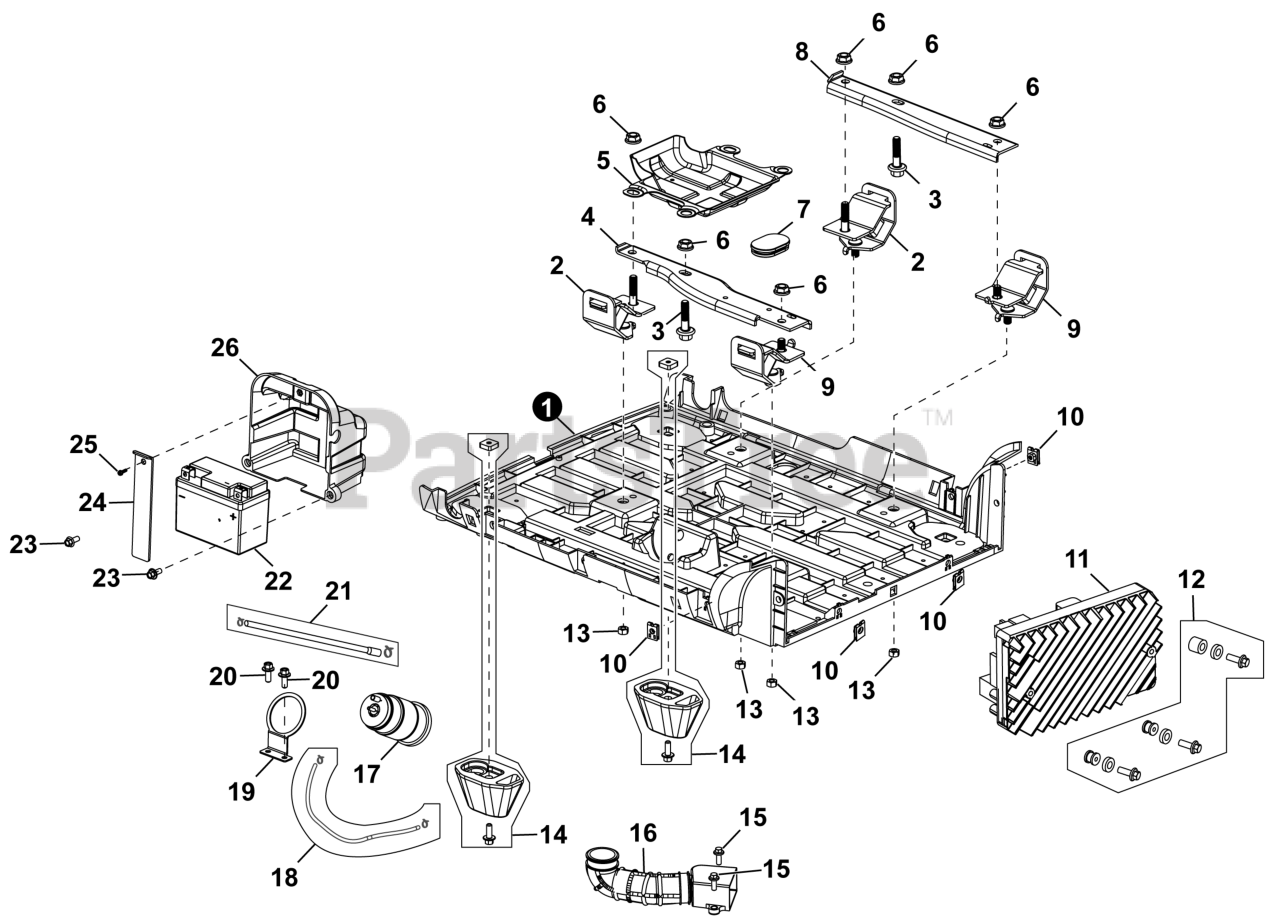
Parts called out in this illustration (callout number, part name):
1	HOUSING, BASE
2	MOUNT, RIGHT ENGINE
4	BRACKET, LEFT SUPPORT
5	DEFLECTOR, CRANKCASE AIR
7	PLUG, END
8	BRACKET, RIGHT SUPPORT
9	MOUNT, LEFT ENGINE
11	INVERTOR
12	KIT, INVERTER MOUNT
14	FEET, FRAME
16	DUCT, AIR CLEANER INTAKE
17	CANNISTER, VAPOR
18	HOSE, AIR CLEANER
19	BRACKET, CANNISTER
21	HOSE, FUEL VAPOR
24	CLAMP, BATTERY
26	CASE, BATTERY
